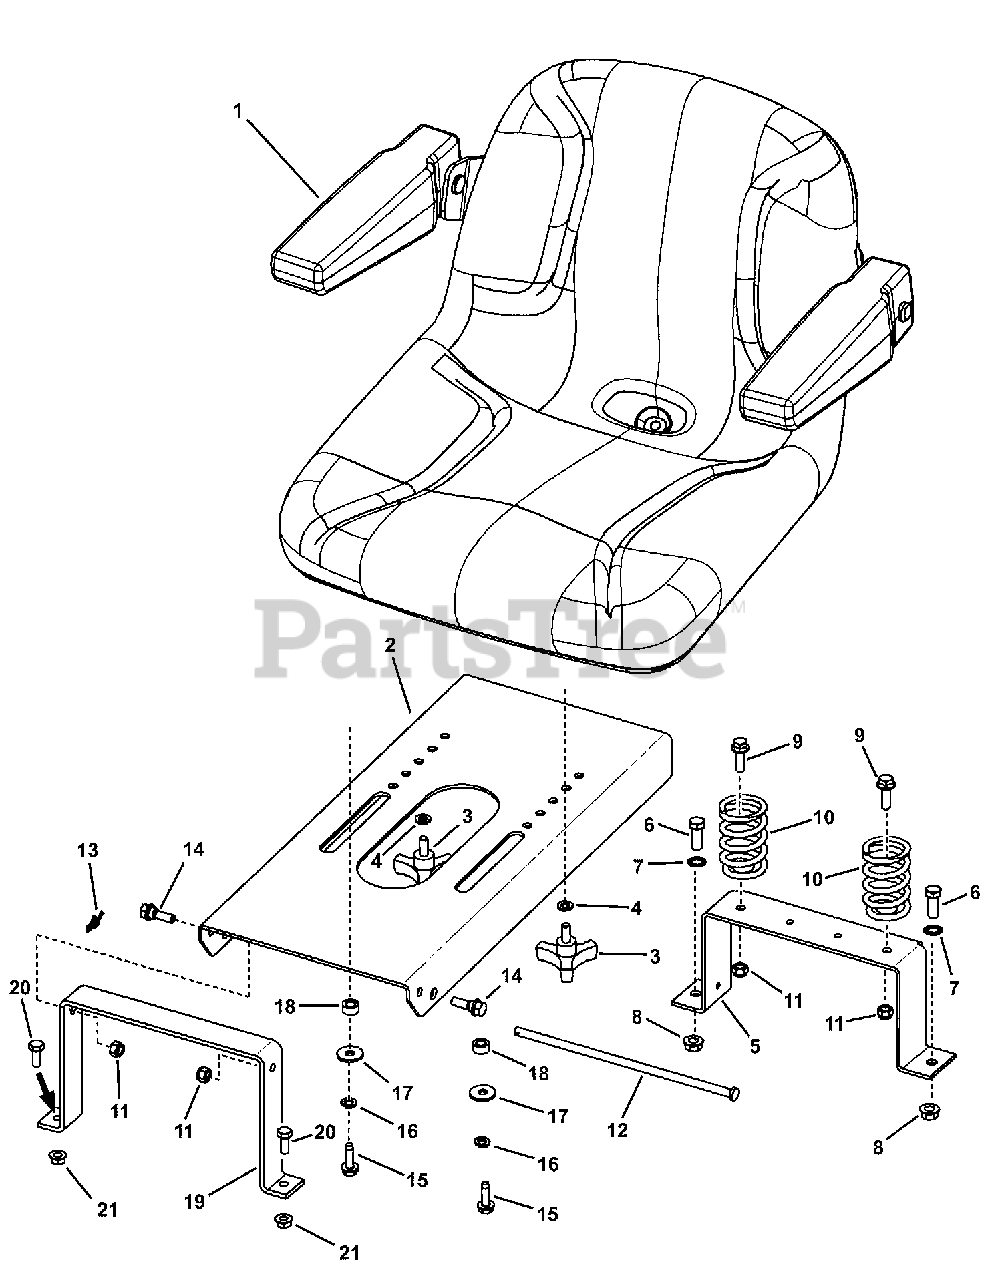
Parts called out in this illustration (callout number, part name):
1	SEAT, 15" Back, w/Armrests
2	PLATE, Seat
3	KNOB, Three Prong 5/16-18X3/4
4	WASHER, Lock, .318X.583X.078 ZP
5	BRACKET, Seat Support
6	CAPSCREW, Hex Head, 3/8C X1 GR5 YZ
7	WASHER, Lock, Internal Tooth, 3/8 BZ
8	NUT, Hex Flange Lock, 3/8C YZ
9	CAPSCREW, Hex Head, Whiz Lock, Flange, 5/16C X1 GR5 YZ
10	SPRING, Compression, Seat Support
11	NUT, Hex, Lock, 5/16C ESNA YZ
12	ROD, Seat Hinge
13	PIN, Cotter
14	BOLT, Shoulder, 5/16C X.704,.435 DIA,YZ
15	CAPSCREW, Hex Head Flange Taptite, 5/16C X1
16	WASHER, Lock, .32X.58X.08 YZ
17	WASHER, .34X1X.09 ZP
18	SPACER, .625 OD X .340 ID X .31 L
19	BRACKET, Lower Seat
20	CAPSCREW, Hex Head, 5/16C X3/4 GR5 YZ
21	NUT, Hex Flange Lock, 5/16C GR5 YZ
